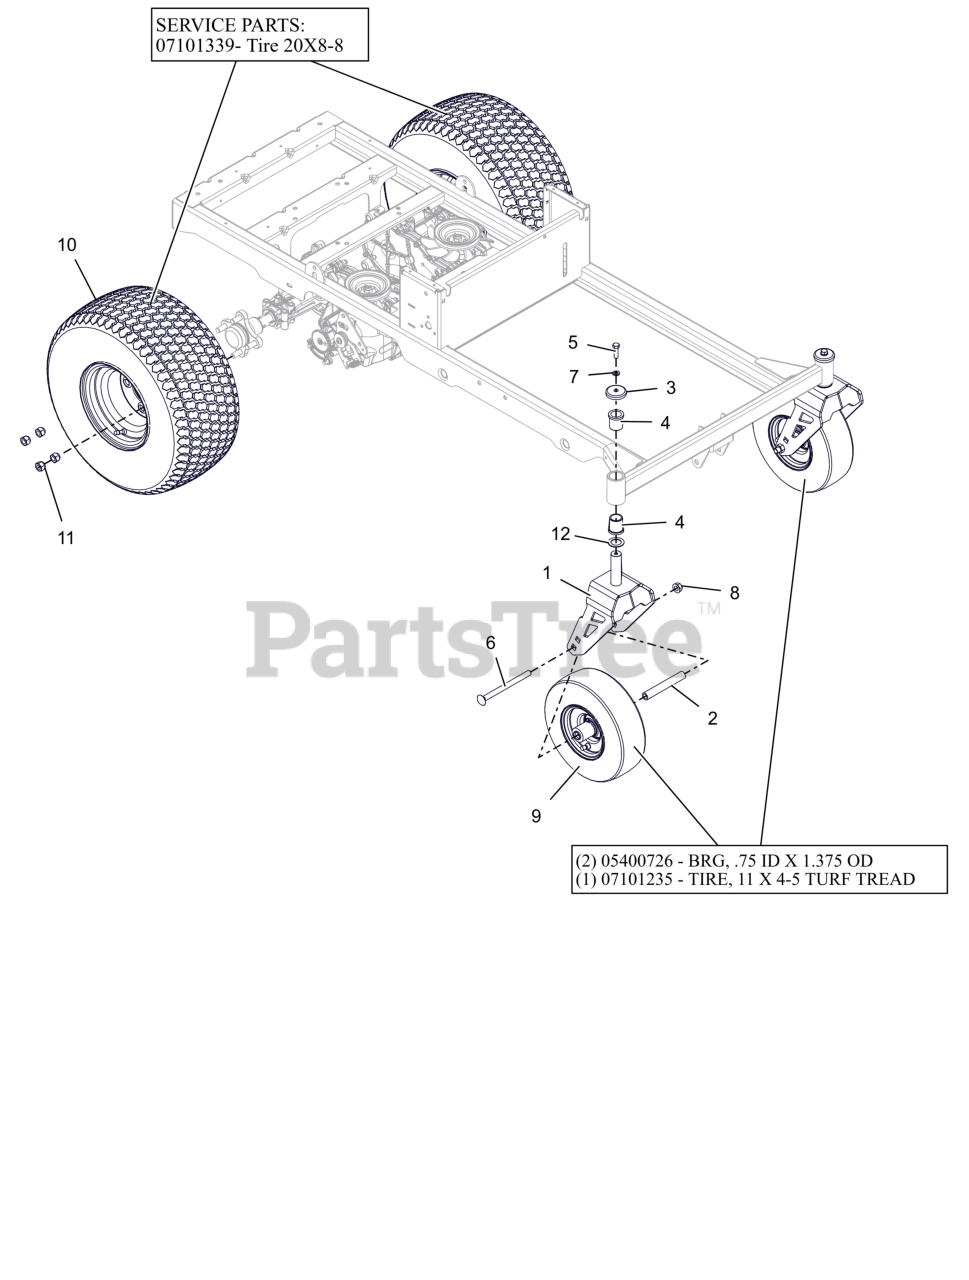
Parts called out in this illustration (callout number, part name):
1	WLDMT, CASTER FORK-XD (ORANGE)
2	SPACER, ROLLED WHEEL
3	SHIELD, AXLE BEARING
4	BSHG-FLG 1.00X1.25X1.50X1.50
5	BLT, HEX .38-16X1.25 G5 ZCC
6	BLT, RHSN .50-13X6.50 G5 ZCC
7	WSHR,LK-REG .375X.094 ZCC
8	NUT-LK-CTR-FLG .500-13 GG ZCC
9	ASM, WHL/TIRE 11X4.00-5
9	BRG, .75 ID X 1.375 OD
9	LAWN TIRE FRONT, 11/4-5 TURF TREAD
9	TIRE TUBE, 11/4.0-5 4 PLY TR87 90 BENT VALVE
10	ASSM TIRE\WHEEL, 20 X 8 -8
10	LAWN TIRE REAR, 4 PLY K505 20/8.00-8
10	TIRE TUBE 18/6.50/8.50/9.50-8, 20/8.00/10.00-8 4 PLY TR13 STRAIGHT VALVE
11	NUT, WHEEL .50-20 ZCC
12	WSHR-HRD-THRS 1.007X1.542X.062
